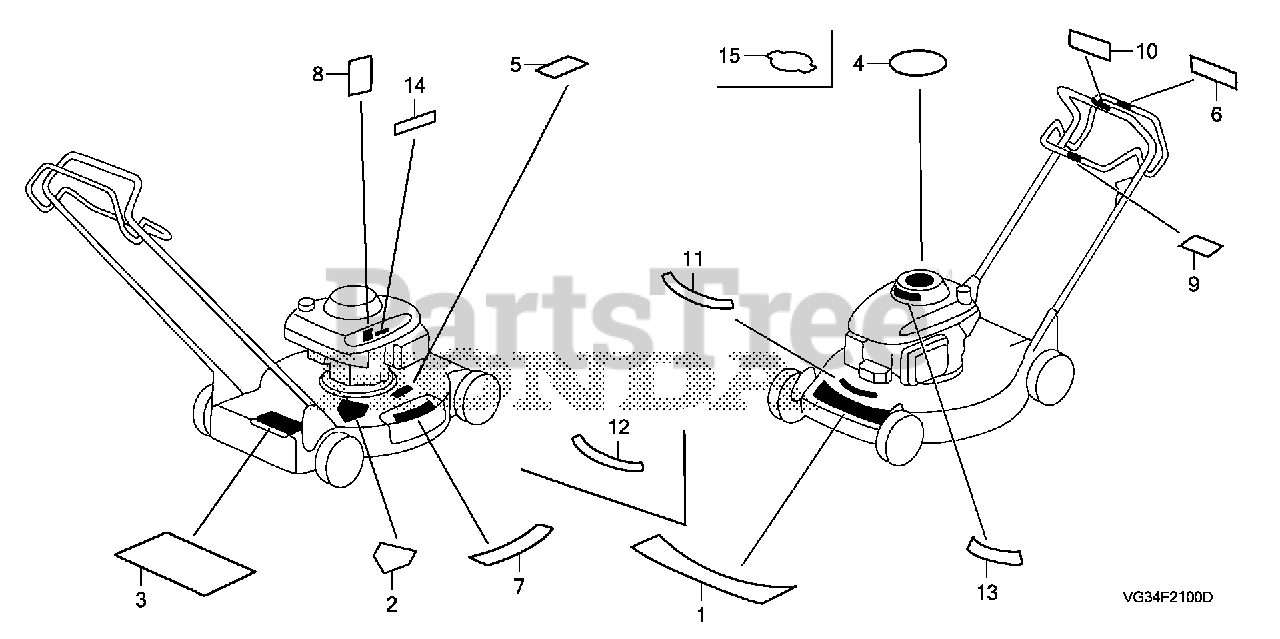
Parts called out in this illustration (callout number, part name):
1	MARK, EMBLEM (HARMONY S)
2	CAUTION C, HOUSING
3	LABEL, WARNING (ENGLISH)
4	PLATE, EMBLEM
5	LABEL, HEAT WARNING
7	LABEL, DISCHARGE GUARD WARNING (ENGLISH)
8	MARK, OIL CAUTION
9	MARK, BLADE CONTROL (ENGLISH)
10	MARK, SALES POINT (ERGOACTIVE) (NOT AVAILABLE)
